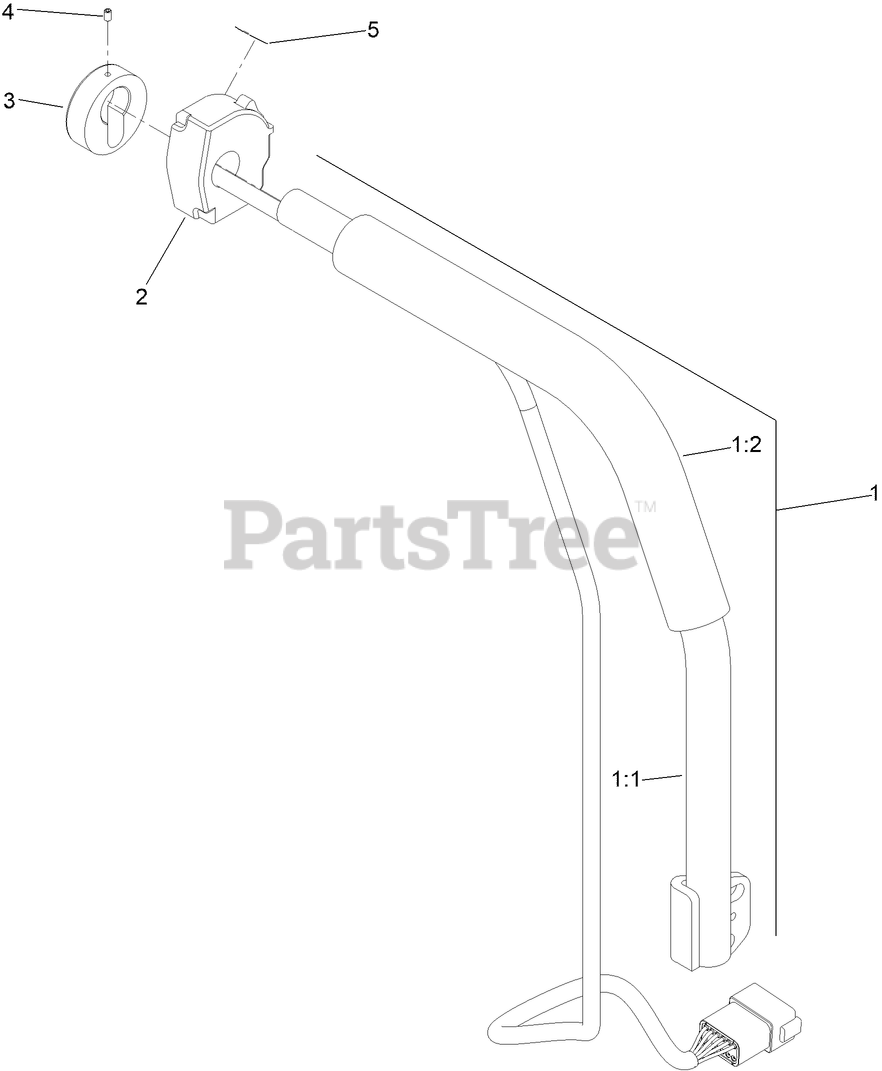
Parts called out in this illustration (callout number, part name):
1	HANDLE ASM - LH
1:1	HANDLE ASM-LH [RED]
1:2	GRIP, CONTROL LEVER
2	SWITCH-COMBINATION ASSEMBLY
3	CAP-SWITCH
4	SCREW-SET
5	DECAL-LIGHTS
